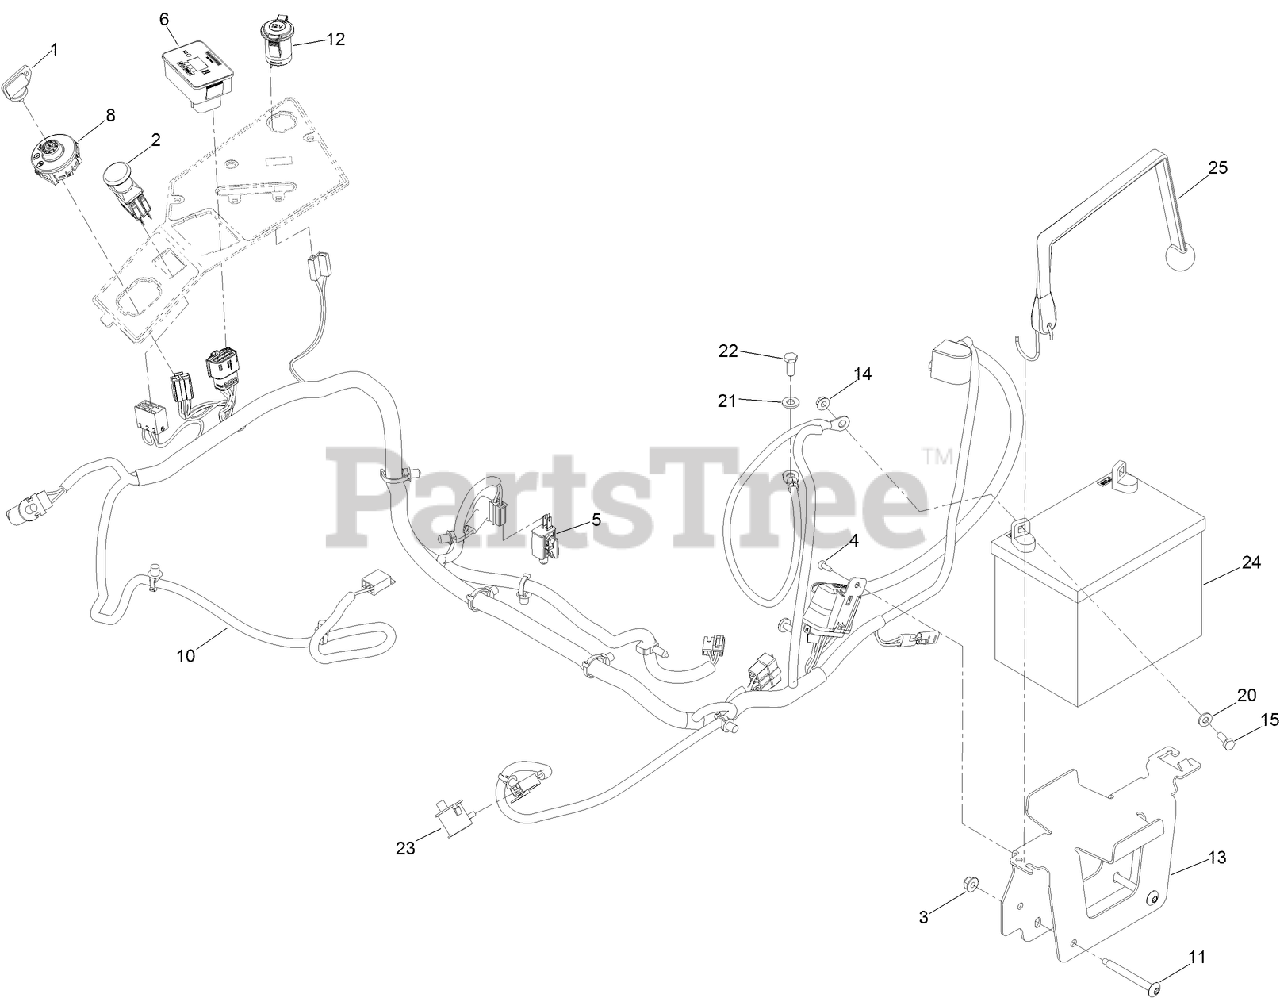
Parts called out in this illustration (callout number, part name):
1	KEY-IGNITION
2	SWITCH-PTO
3	NUT-HF, NI
4	SCREW-FORMING, THREAD
5	SWITCH
6	MODULE ASM
8	SWITCH-IGNITION
10	HARNESS-WIRE
11	SCREW-TORX
12	PORT-POWER, 12V
13	TRAY-BATTERY
14	NUT-HF
15	SCREW-HH
20	WASHER-FLAT
21	WASHER-PLAIN
22	SCREW-HH
23	SWITCH-BAIL
24	BATTERY (300 CCA, WET)
25	STRAP-BUNGEE
